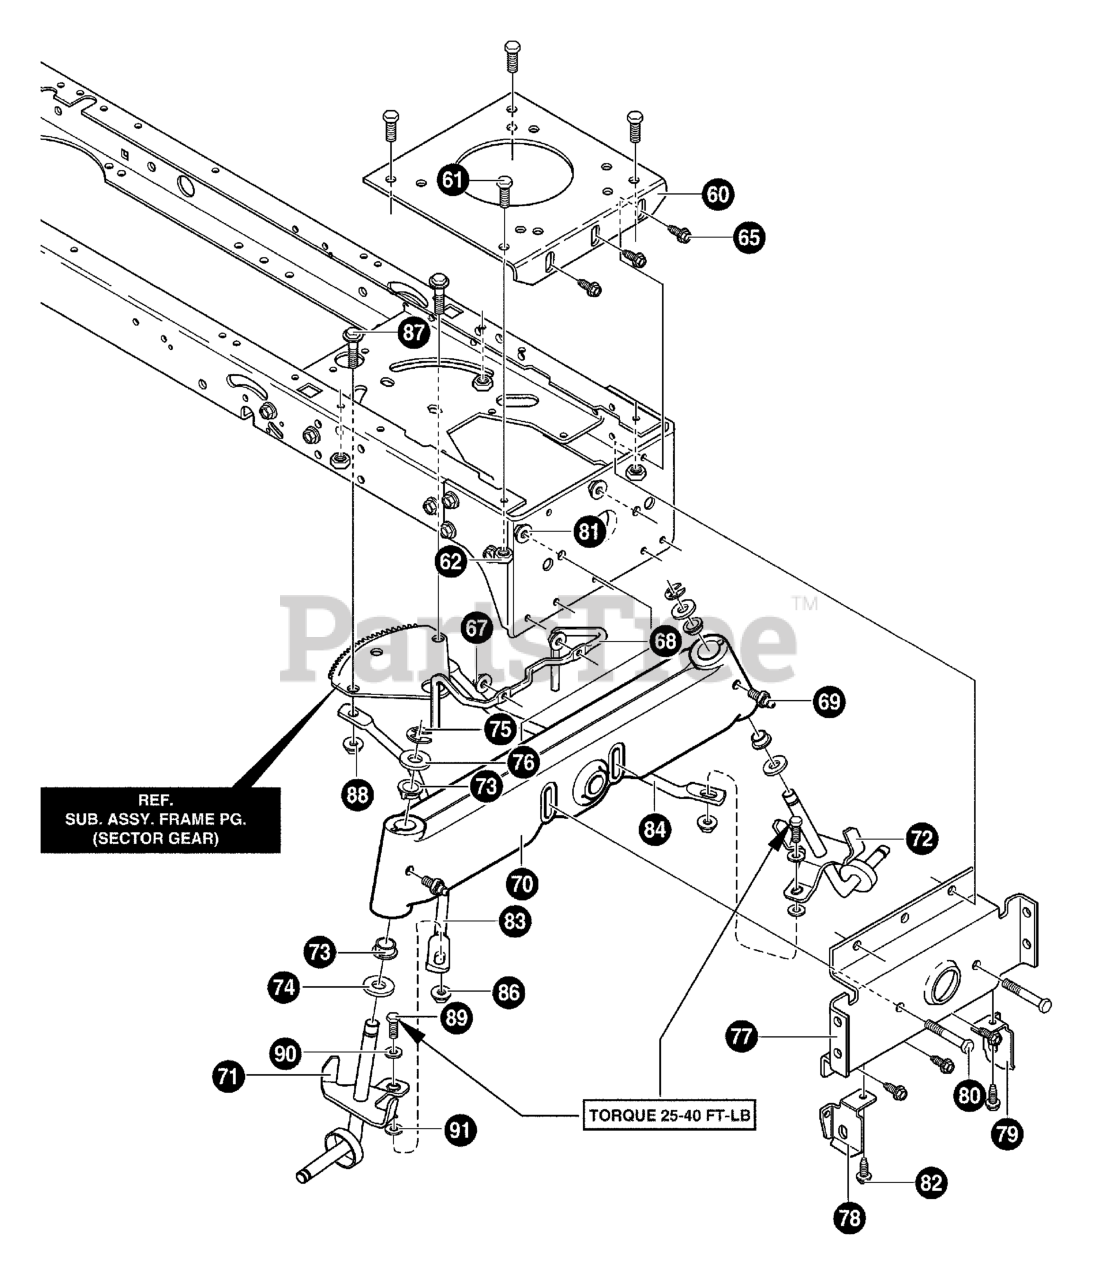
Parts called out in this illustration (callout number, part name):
60	PLATE, ENGINE
61	SCREW, 5/16-18 x .75 HHWATAP
62	NUT, 5/16-18 WDFLLK
65	SCREW, 5/16-18 x .75 HHWATAP
67	NUT, 5/16-18 HEXWDFLLK WHIZ
68	GUIDE-STACK PULLEY BELT
69	ZERK, GREASE FITTING
70	AXLE, CAST MACHINED
71	SPINDLE, LONG RH
72	SPINDLE, LONG LH
73	BEARING, SPINDLE
74	WASHER, .766IDX1.62ID
75	E-RING .574IDX.050/.750 SH
76	WASHER, FLAT .765 x 1.81 x .059
77	HANGER, AXLE
78	HANGER, DECK RH
79	HANGER, DECK LH
80	SCREW 5/16-18X3.00
81	NUT, 5/16-18 WDFLLK
82	SCREW, 5/16-18 x 0.75 HHWATAP
83	DRAG LINK LH
84	DRAG LINK RH
86	NUT, 3/8-16 HWDFLLK MACK
87	BOLT, HHSH
88	NUT, 3/8-16 HWDFLLK MACK
89	SCREW, 3/8-16 x 1.50
90	WASHER, FLAT .391X1.00X.083
91	WASHER, FLAT .406X.81X16
